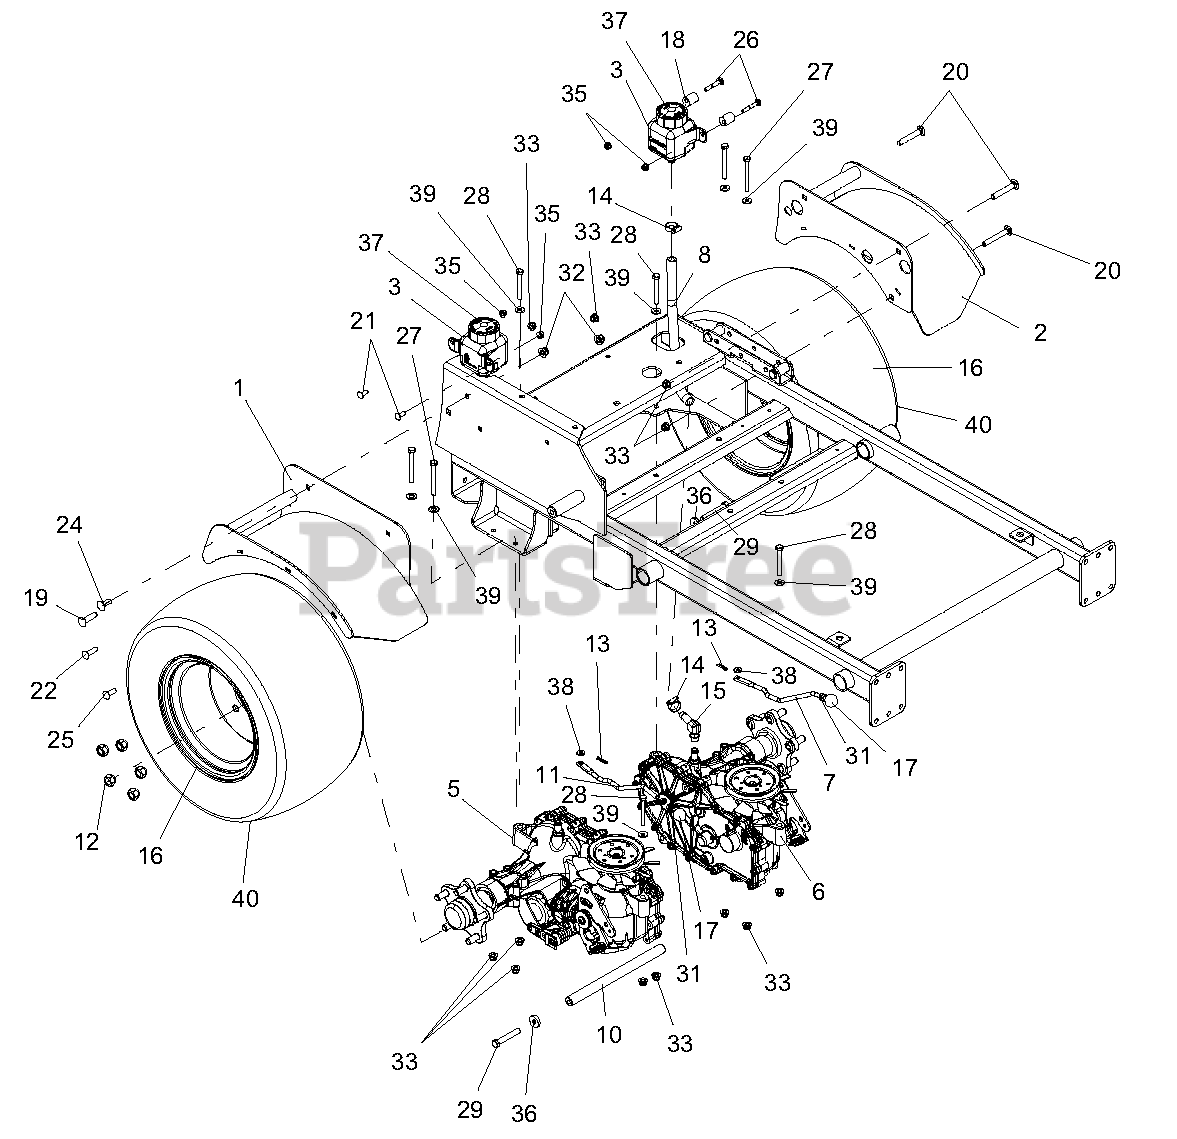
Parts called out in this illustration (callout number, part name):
1	WLDMT, RH FENDER
2	WLDMT, LH FENDER
3	TANK, EXPANSION ZT2800 (INC. ITEM 37)
5	TRANSAXLE, 3400 PRO-STANCE, RH
6	TRANSAXLE, 3400 PRO-STANCE, LH
7	ROD, DUMP VALVE LH
8	ROSE, HYD OVERFLOW
10	SHAFT, CROSS BRACE
11	ROD, DUMP VALVE RH
12	NUT 1/2-20 LUG C
13	PIN HAIR
14	CLAMP .88 DIA HOSE
15	FITTING HYD (90 DEG)
16	ASSM TIREWHEEL, 20X10.50X.8 (INC ITEM 40)
17	KNOB BALL BLACK .312-18
18	ECCENTRIC
19	BLT RDHDSQNK .38-16X1.50 G5 Y
20	BLT RDHDSQNK .38-16 X 2.75 G5 Y
21	BLT RDHDSQNK .25-20 X .75 G5 YWZC
22	BLT RDHDSQNK .31-18 X 1.25 G5 Y
24	BLT RDHDSQNK .38-16 X 1.00 G5 YWZC
25	BLT RDHDSQSHNK .31-18X1.00 G5 Y
26	BLT RDHDSQNK .25-20 X 1.75 G5
27	BLT HEX .31-18 X 3.00 GR5 YWZC
28	BLT HEX .31-18 X 2.50 GR5 YWZC
29	BLT HEX .38-16 X 2.50 GR5 YWZC
31	NUT 5/16-18 JAM GR5 Y
32	NUT LK NYL FLG .38-16 YWZC
33	NUT LK NYL FLG .31-18 YWZC
35	NUT LK NYL FLG .25-20 YWZC
36	WSHR FL STL .406 X 1.00 X .188 YWZC
37	CAP, HYDRO RESERVOIR REPLAC
38	WSHR FL STL .281 X .62 X .065 YWZC
39	WSHR FL STL .312 X .734 X .065 YWZ
40	TIRE, 20 X 10.5-8 4P K500
